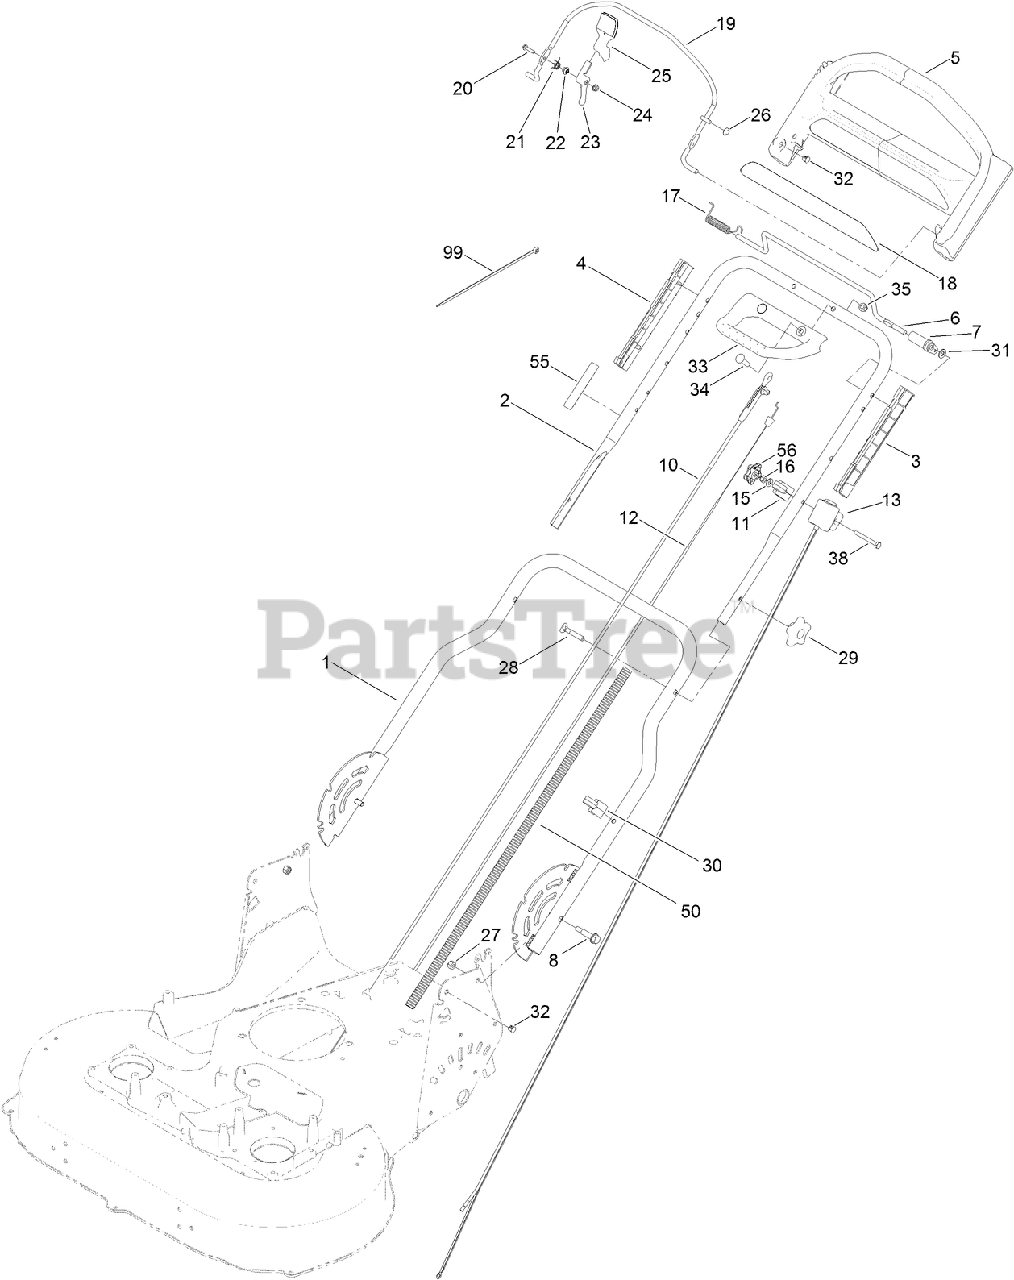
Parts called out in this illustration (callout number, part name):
1	HANDLE-LOWER
2	HANDLE-UPPER
3	GUIDE-LH
4	GUIDE-RH
5	HANDLE-CONTROL
7	LEVER-TRACTION
8	BOLT-SHOULDER, HHF
12	CABLE-TRACTION
13	SWITCH HOUSING ASM
15	WASHER-FLAT
16	NUT-LOCK, NI
18	DECAL-HANDLE
19	BAIL-BRAKE
20	SCREW-HWH
21	SPRING-TORSION
22	SPACER
23	LEVER
24	NUT-LOCK, FLANGE
26	NUT-SPEED
27	NUT-LOCK, NI
28	SCREW-HANDLE
29	KNOB-HANDLE
30	GUIDE-CABLE
31	SPACER
32	PLUG-DOME
33	HANDLE-ASSIST, TRACTION
34	BOLT-CARRIAGE
35	NUT-ACORN
38	SCREW-HH
50	CONDUIT-CONVOLUTED
56	KNOB-HANDLE, LOCKING
99	TIE-CABLE
